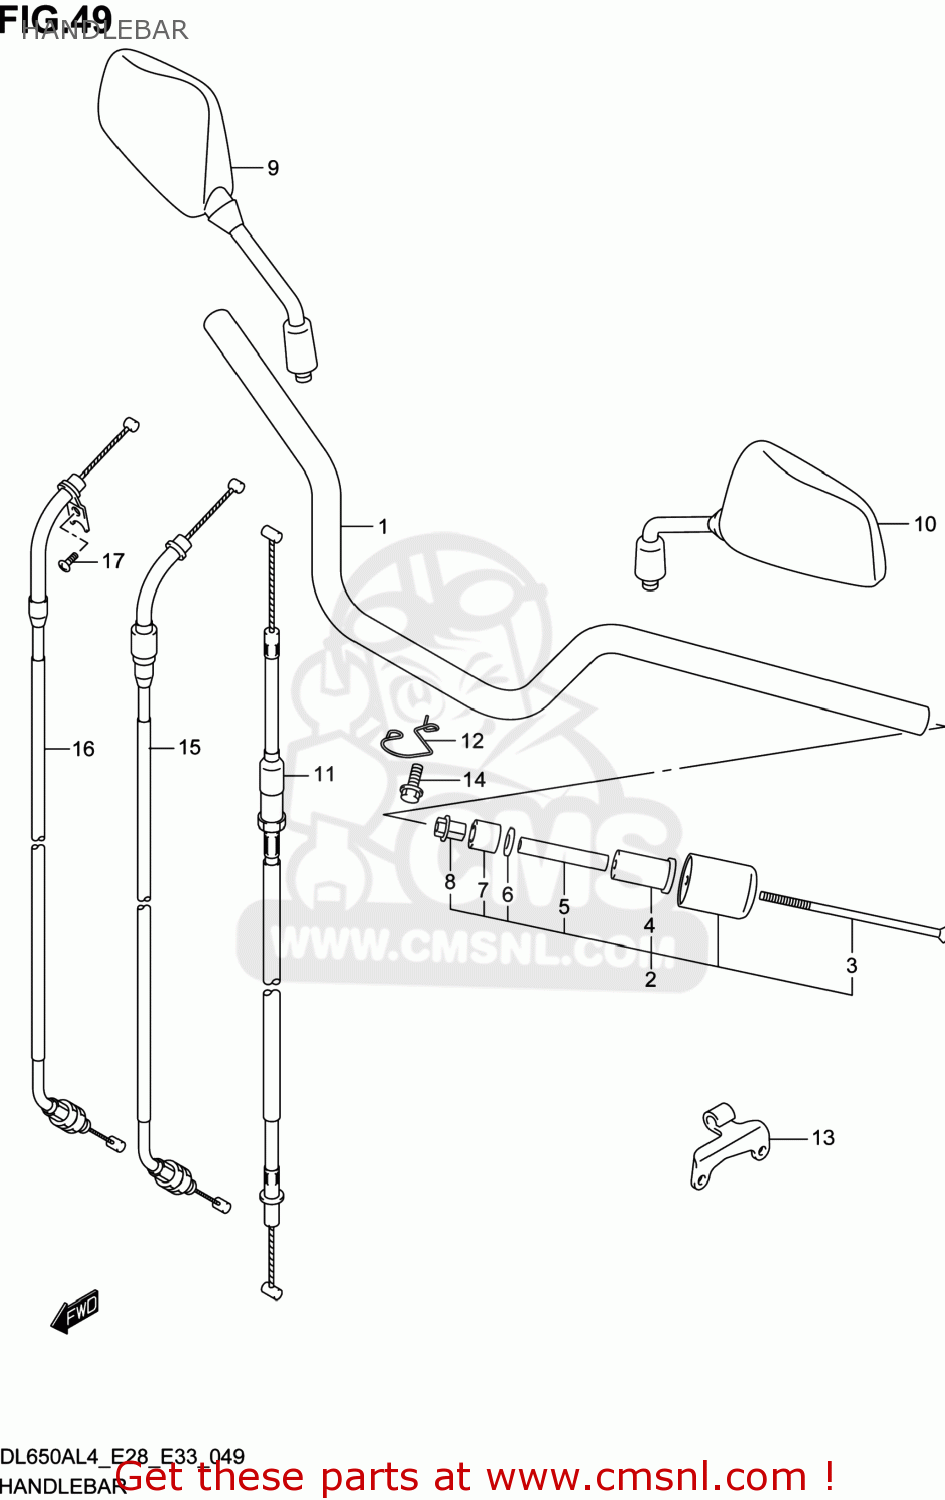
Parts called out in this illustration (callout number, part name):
1	HANDLEBAR(SILVER)
2	BALANCER SET,HANDLEBAR
3	SCREW(6X110)
4	EXPANDER
5	SPACER,EXPANDER
6	WASHER(6.5X16X4)
7	EXPANDER,HANDLE BALANCER
8	NUT,HANDLE BALANCER
9	MIRROR ASSY,RR VIEW,R
10	MIRROR ASSY,RR VIEW,L
11	CABLE ASSY,CLUTCH
12	GUIDE,CLUTCH CABLE
13	STOPPER,CLUTCH CABLE
14	BOLT
15	CABLE ASSY,THROTTLE NO.1
16	CABLE ASSY,THROTTLE NO.2
17	SCREW(5X10)
